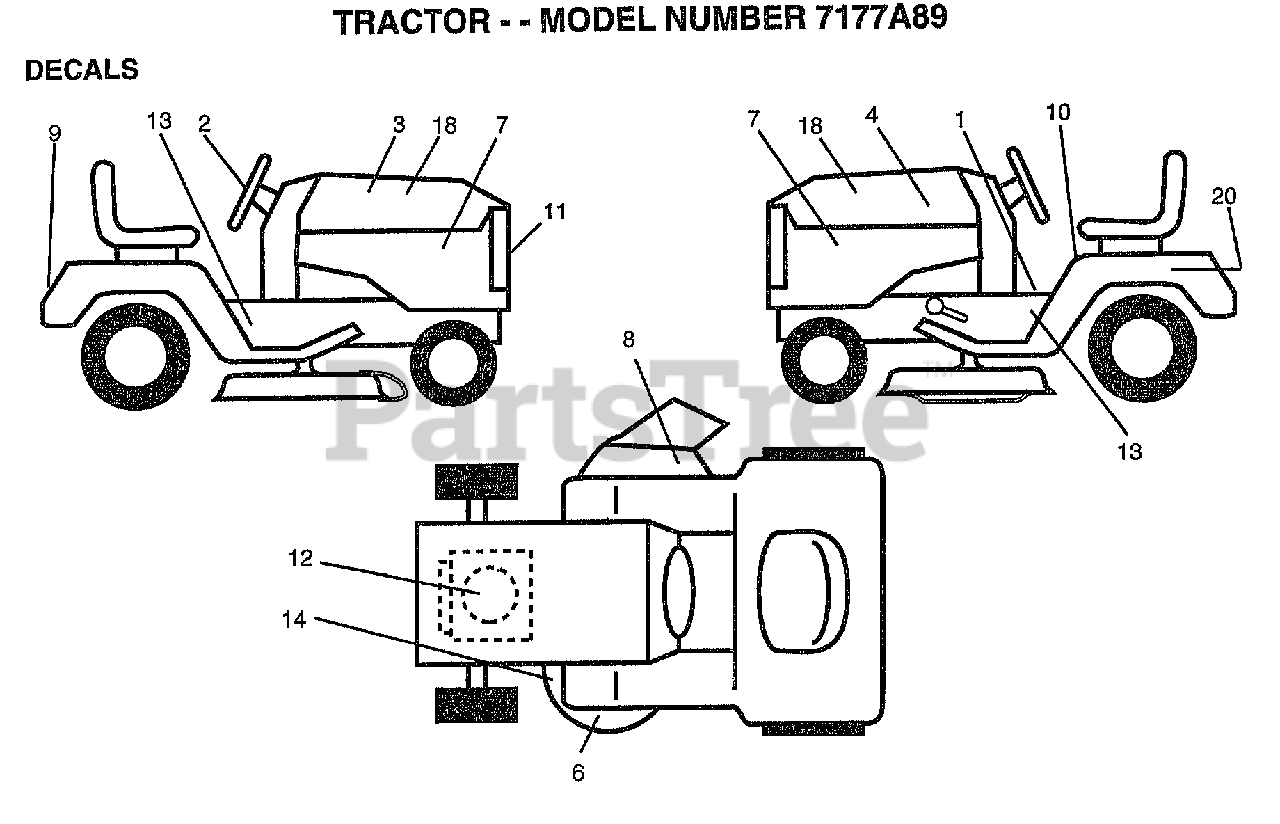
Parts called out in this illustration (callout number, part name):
1	"DECAL-DASH,OPER"
2	DECAL STEER WHL
3	DECAL HOOD RH
4	DECAL HOOD LH
5	DECAL, HP ENGINE
6	DECAL DECK MULCH
8	DECAL DECK WIZ +
10	"DECAL DANGER,FEND"
11	DECAL.LENS.WIZARD
13	DECAL CHASSIS WIZ
14	"DECAL-SCHEM,BELT"
18	NAMEPLATE.HD.WIZA
20	DECAL.BATRY.3-3908
